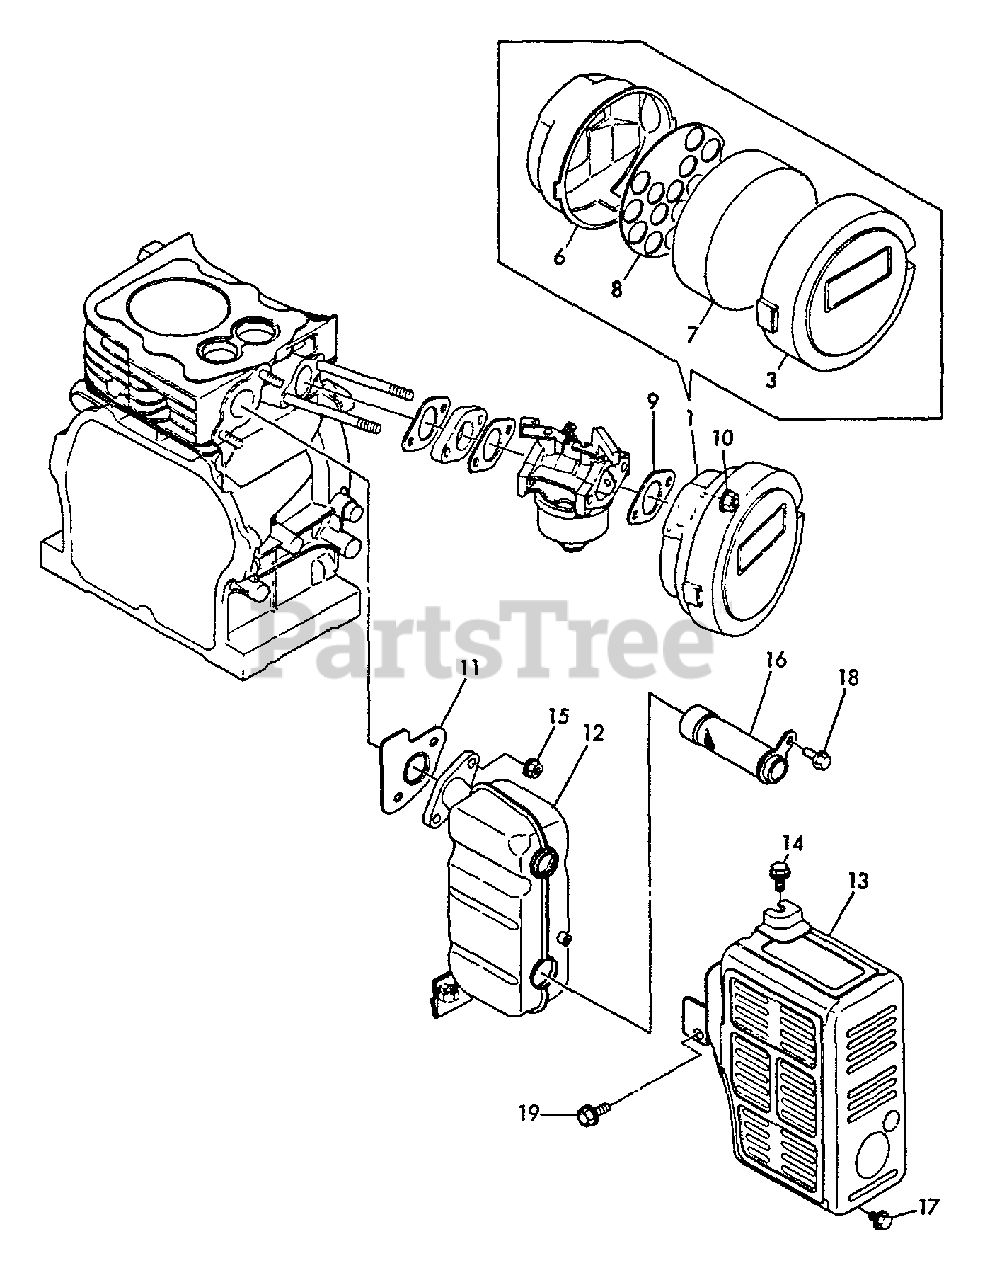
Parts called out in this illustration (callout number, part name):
1	AIR CLEANER ASSY
3	COVER, AIR FILTER
6	CASE, AIR FILTER
7	FILTER, AIR
8	RETAINER, AIR FILTER
9	GASKET, INTAKE
10	NUT - 6 -- FLANGE
11	GASKET, EXHAUST
12	MUFFLER
13	COVER, MUFFLER
14	BOLT - 6X8 -- PLATED
15	NUT - 6 -- FLANGE
16	SCREEN, SPARK ARRESTOR
17	BOLT - 6X8 -- PLATED
18	BOLT - 6X10 -- PLATED
19	BOLT - 8X14 -- PLATED
